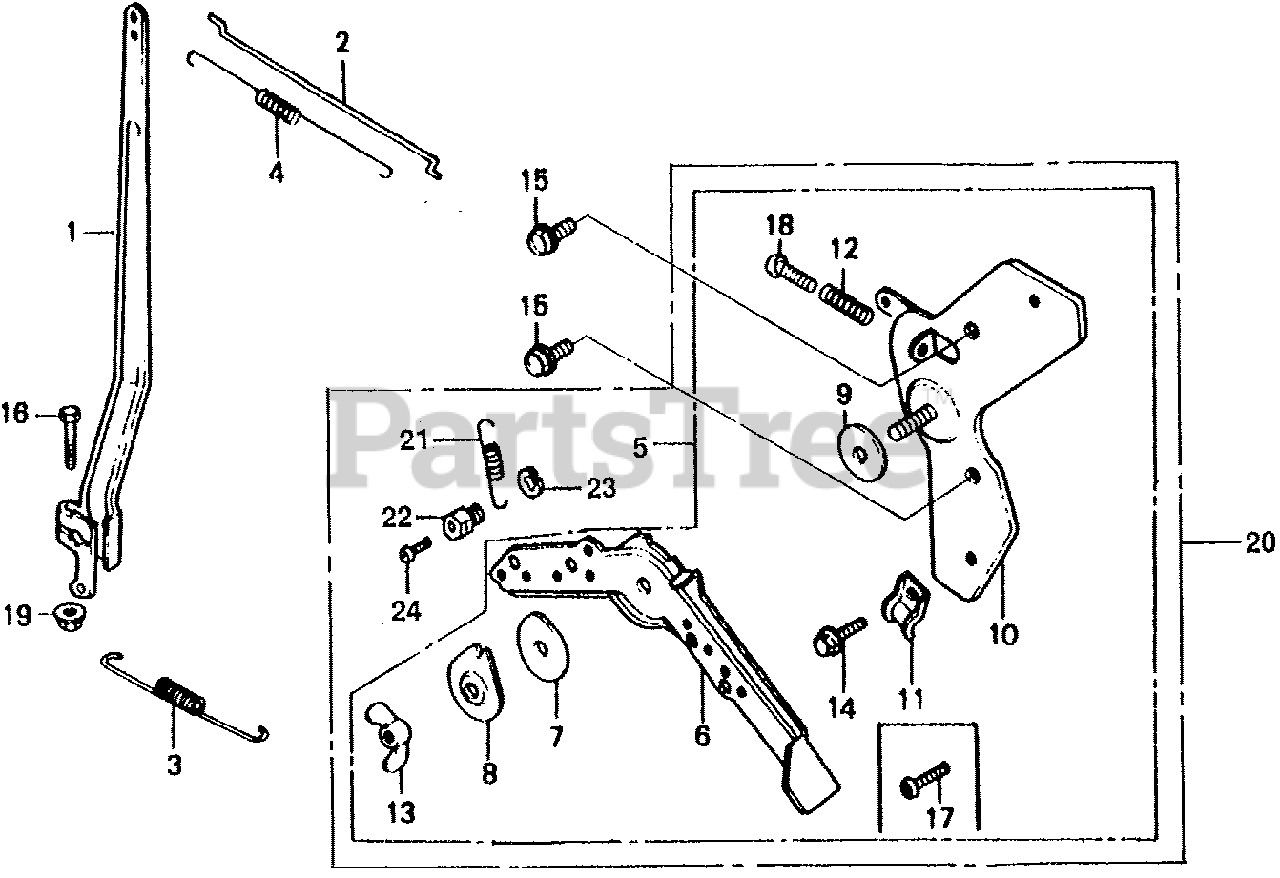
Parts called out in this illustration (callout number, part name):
1	ARM, GOVERNOR
2	ROD, GOVERNOR
3	SPRING, GOVERNOR
4	SPRING, THROTTLE RETURN
5	CONTROL ASSY.
6	LEVER, CONTROL
7	SPRING, LEVER
8	WASHER, CONTROL LEVER
9	SPACER, CONTROL LEVER
10	BASE, CONTROL LEVER
11	HOLDER, CONTROL CABLE
12	SPRING, CONTROL ADJUSTING
13	WINGNUT (6MM)
14	BOLT, FLANGE (5X10)
15	BOLT, FLANGE (6X12) (CT200)
16	BOLT, GOVERNOR ARM
17	SCREW, PAN (5X10)
18	SCREW, PAN (5X22)
19	NUT, FLANGE (6MM)
20	CONTROL ASSY.
21	SPRING, CABLE RETURN
22	HOLDER, WIRE
23	CIRCLIP (5MM)
24	SCREW, PAN (4X6)
